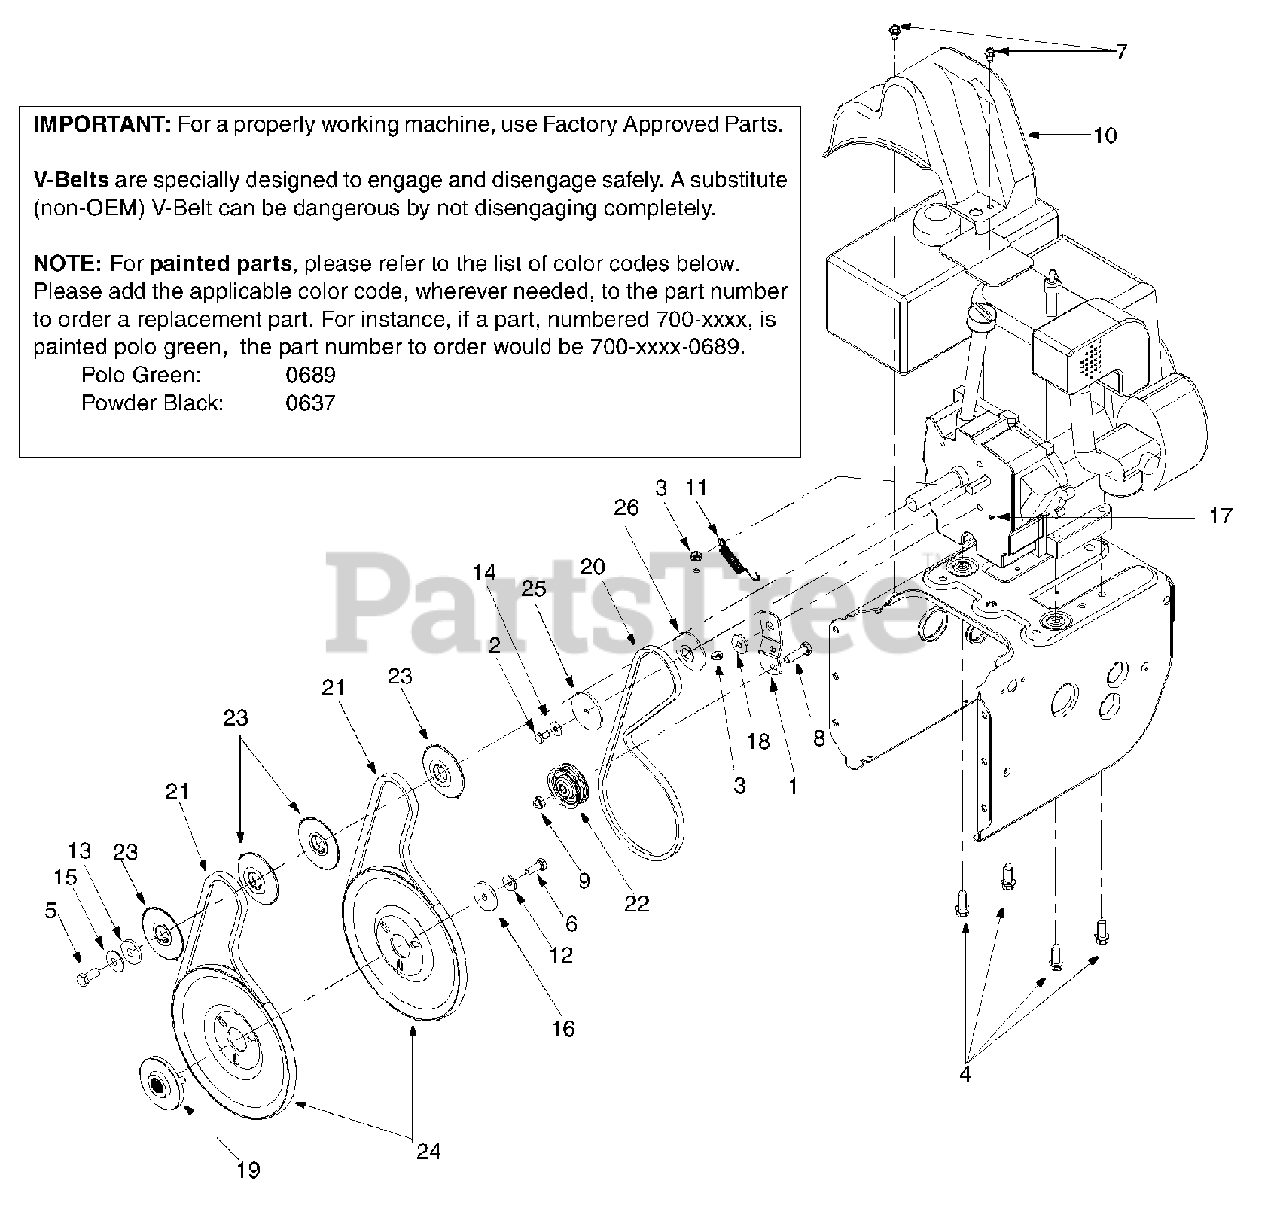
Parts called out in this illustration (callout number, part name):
3	Hex Screw w/ patch: 5/16-24 x 0.75"
4	Hex Washer Head TT Sems Screw
5	Hex Bolt 3/8-24 x .875" Gr.8
6	Hex Screw w/ Patch: 5/16-24 x .875"
7	Hex Washer Head TT
8	Hex Screw: 3/8-16 x 1.0"
9	Top Lock Jam Nut: 3/8-16
10	Belt Cover
11	Extension Spring
12	Belleville Washer
13	Flat Washer
14	Bell Washer
15	Bell Washer
16	Flat Washer
17	Grease
18	Shoulder Spacer
19	Adapter Pulley
20	V-Belt
21	Belt
22	Flat Idler
23	Pulley Half
24	Auger Pulley
25	Pulley Half
26	Pulley Half
